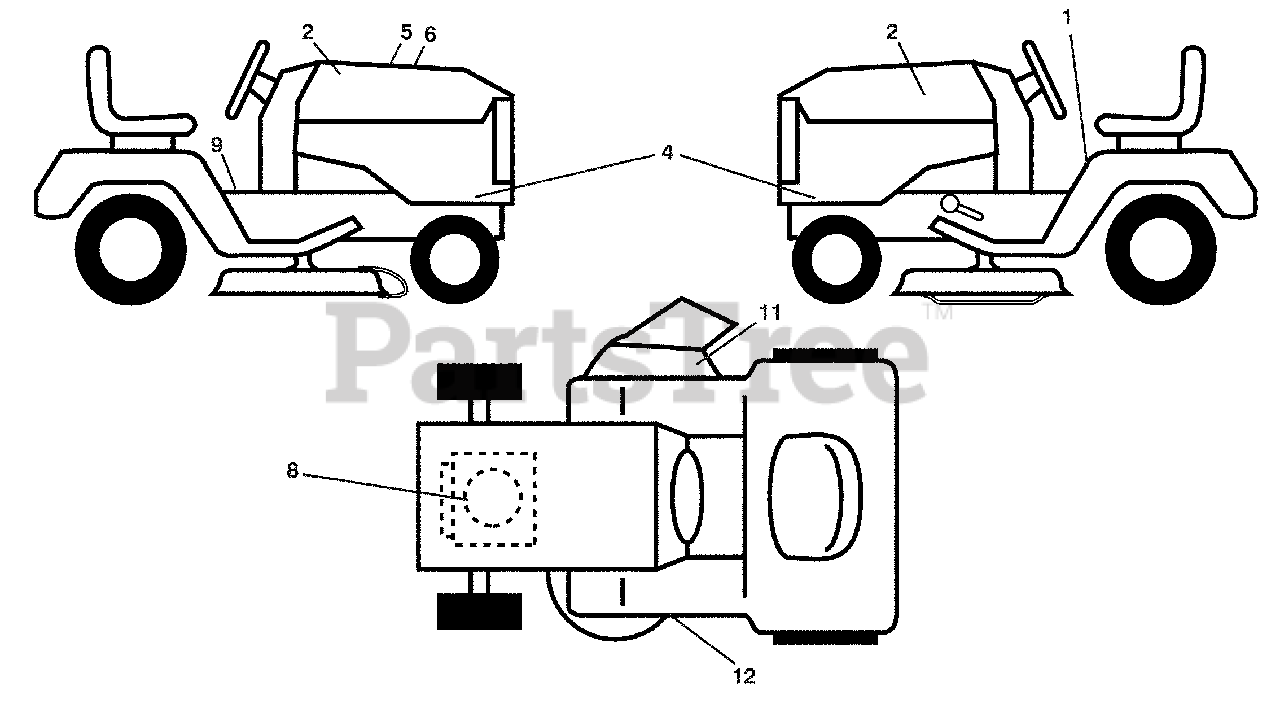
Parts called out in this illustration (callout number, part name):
1	Decal, Fender Warn./Instructions
2	Decal, Hood Logo
4	Decal, Hood Panel
5	Decal, Customer Respons.
6	Decal, Replacement
8	Decal, Engine
9	Decal, Battery Dnge/Poi
11	Decal, Warning
12	Decal, Mower V-Belt Schematic
